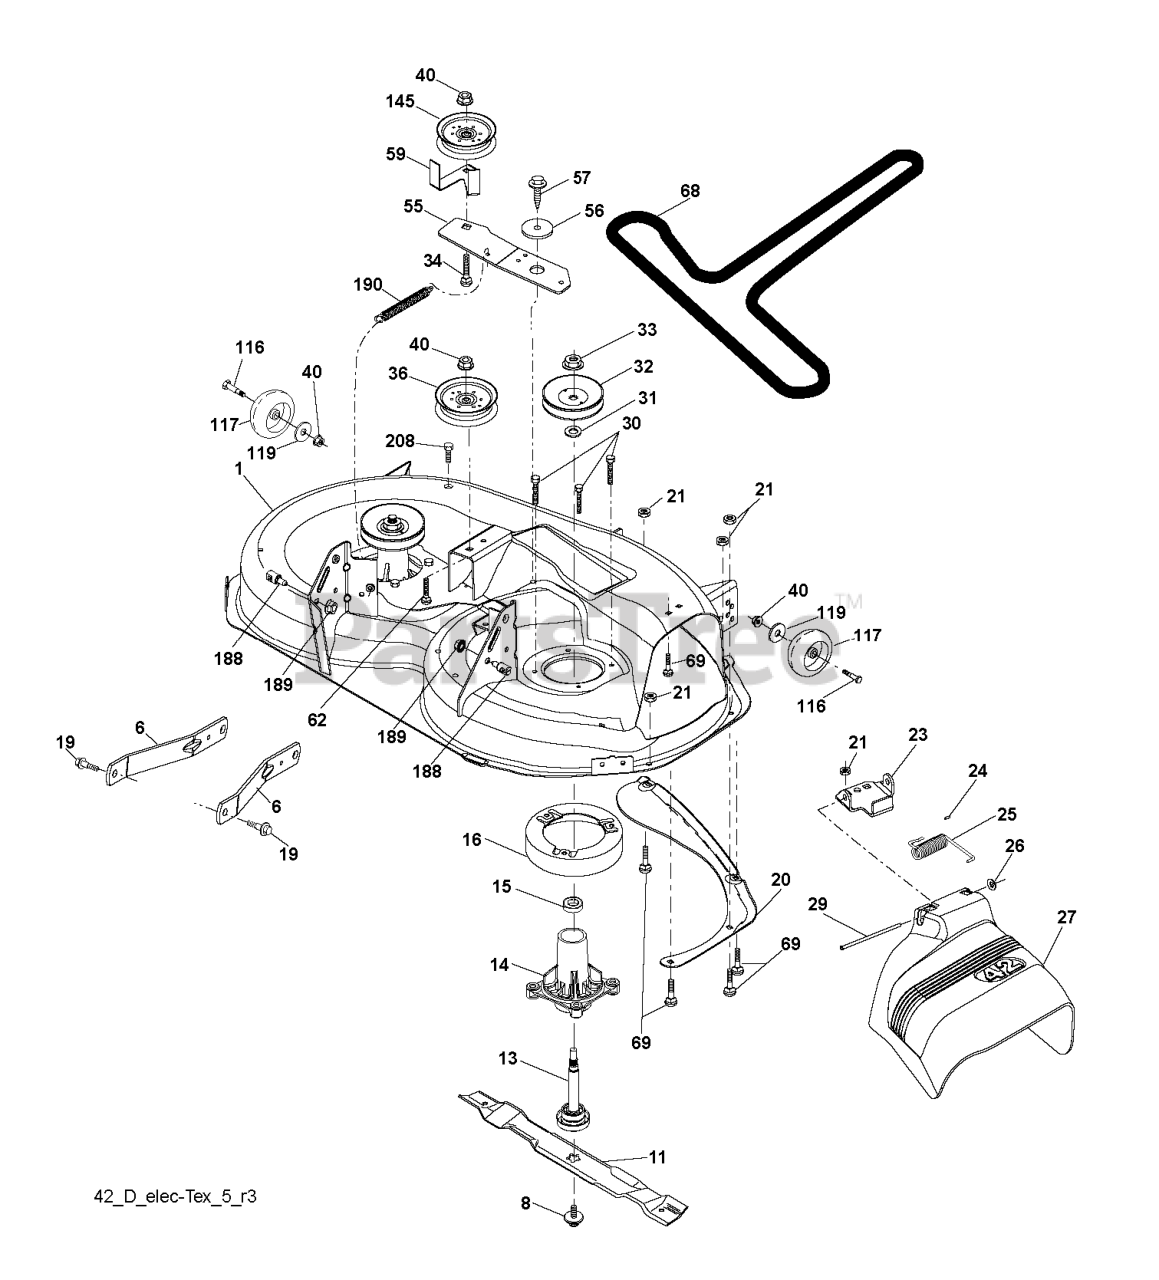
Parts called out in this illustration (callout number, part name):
1	DECK.WELDMENT.42"
6	ARM.SUSPENSION.MOWER.R
8	BOLT.WASHER.ASM.7/16-2
11	42" HI-LIFT BLADE
13	SHAFT.ASM.MDRL.N/GREASE.38
14	RP.HOUSING.MANDREL.4PT.
16	STRIPPER.MANDREL.ROUND.BLACK
19	BOLT.SHOULDER
20	BAFFLE.VORTEX
21	LOCKNUT
23	BRKT.DEFLECTOR.38"2005+
24	CAP-SLEEVE LT
25	SPRING.TORSION.DEFLECT
26	NUT PUSH M
27	SHIELD.DEFLECTOR.MOWER.42"BLAC
29	ROD.HINGE
30	SCREW, WASHER HEAD
31	WASHER.SPACER.MANDREL
32	PULLEY/MANDREL
33	NUT.FLANGE.LOCK.TOP
34	BOLT.3/8-16X1.50
36	PULLEY.IDLER.2006
40	NUT LOCK FLG 3/8-16 UNC
55	IDLER.ARM
56	SPACER.RETAINER
57	SCREW 3/8-16X1
59	GUARD, BELT
62	BOLT
68	BELT V SECONDARY
69	BOLT
116	BOLT M
117	WHEEL.GAGE.HALF.SPOKED
119	WASHER.5/16.FLAT.STE.STD.
145	PULLEY.IDLER.48"PRIMARY
188	STUD.FASTNER.W/ANTI-ROTATE
189	NUT LOCK HEX FLANGE 5/16-18
190	SPRING.MOWER.DRIVE.ELECTRIC
208	SCREW 3/8-16X1/2
